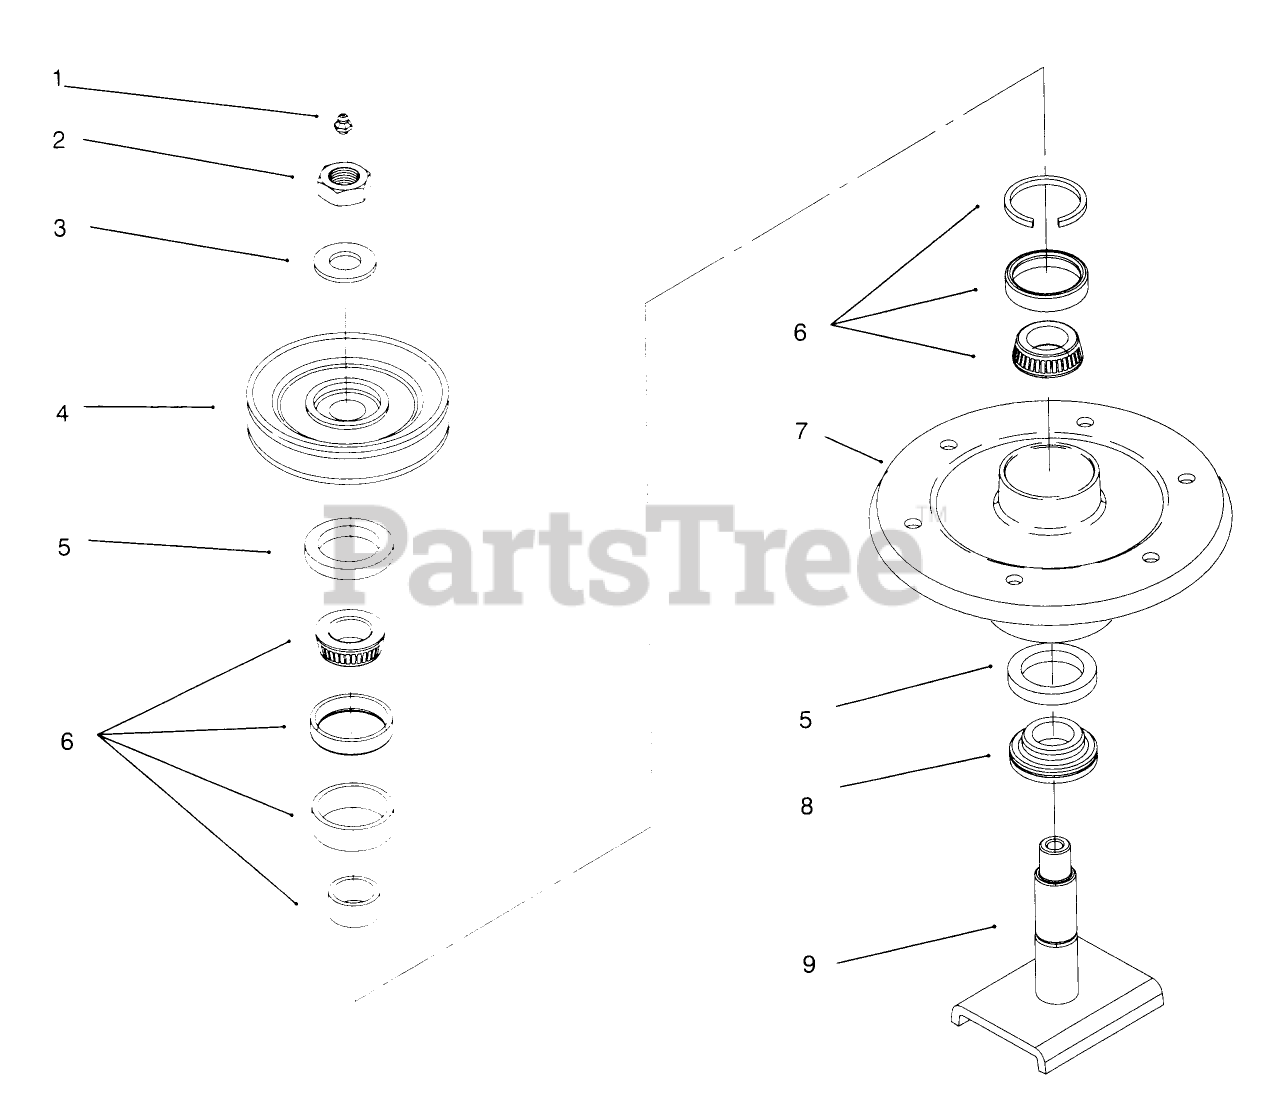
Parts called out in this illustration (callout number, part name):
1	FITTING-GREASE
2	NUT-HEX
3	WASHER
4	PULLEY AND HUB ASM
5	SEAL-OIL
6	BEARING ASM
7	HOUSING-SPINDLE
8	SPACER
9	SHAFT
